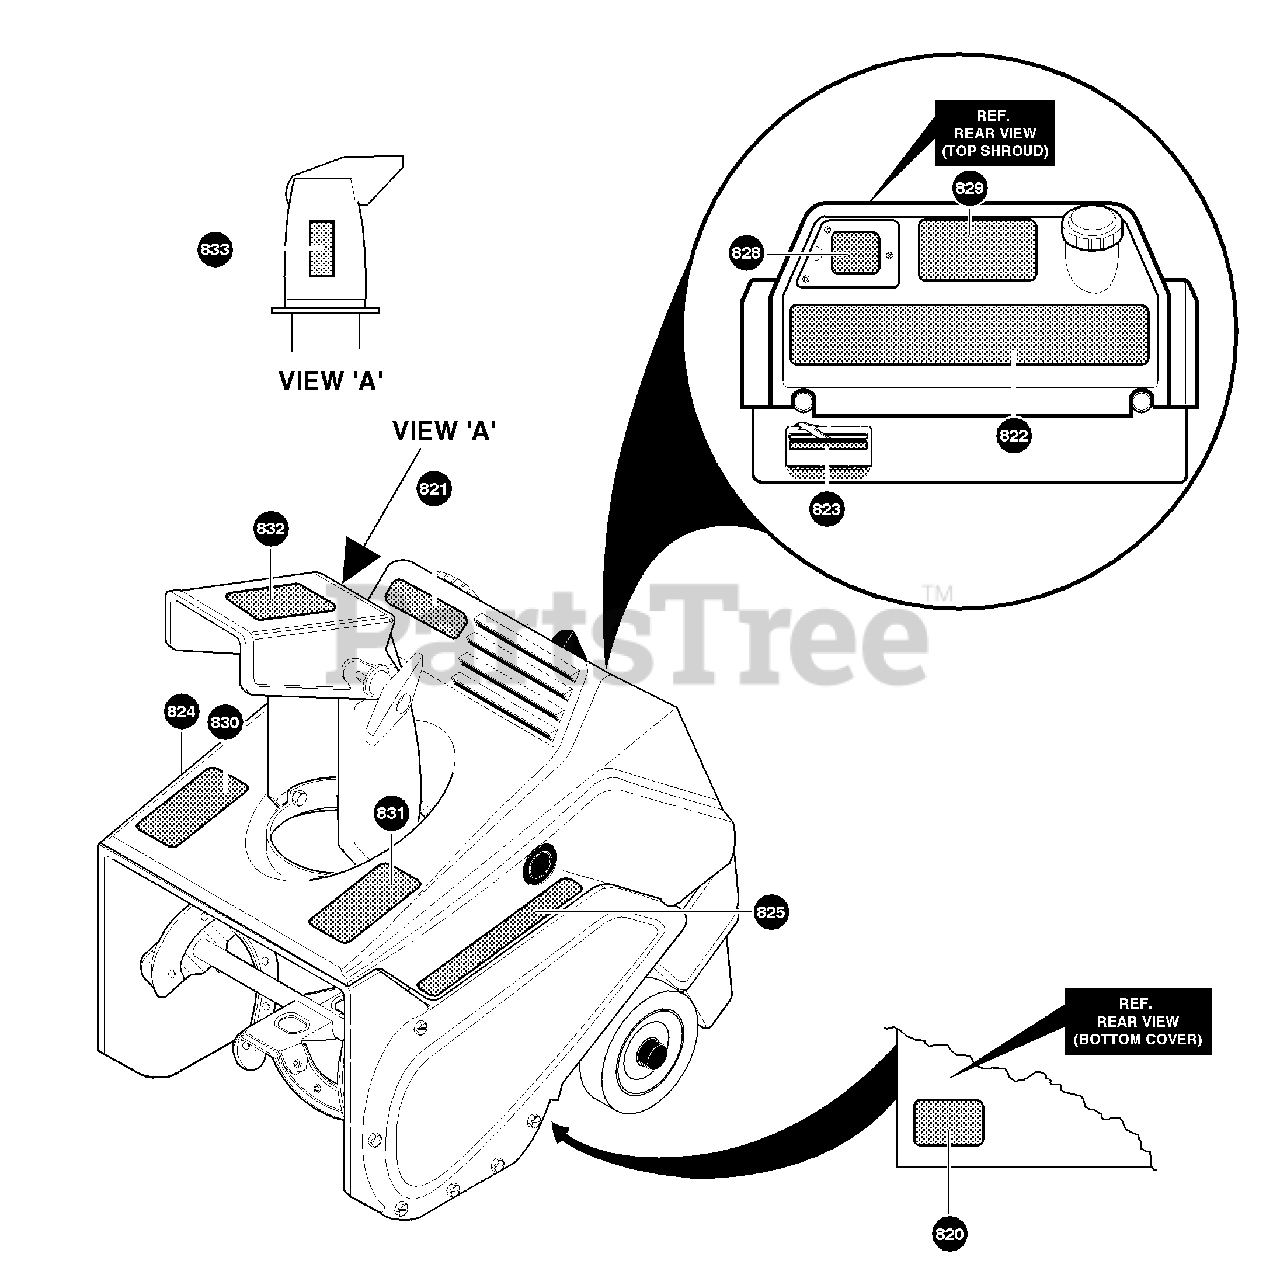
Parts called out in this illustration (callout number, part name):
820	REFERENCE ONLY
821	DECAL, HUSQVARNA
822	DECAL, CONTROL PANEL
823	DECAL, OFF-CHOKE-ON
824	DECAL, RH SHROUD SIDE
825	DECAL, LH SHROUD SIDE
828	DECAL, FUEL MIX
829	DECAL, START INSTRUCTIONS
830	DECAL, DANGER CHUTE ENG/FR
831	DECAL, DANGER AUGER ENG/FR
832	DECAL, HUSQVARNA CROWN
833	DECAL, SAFETY INSTRUCTIONS
